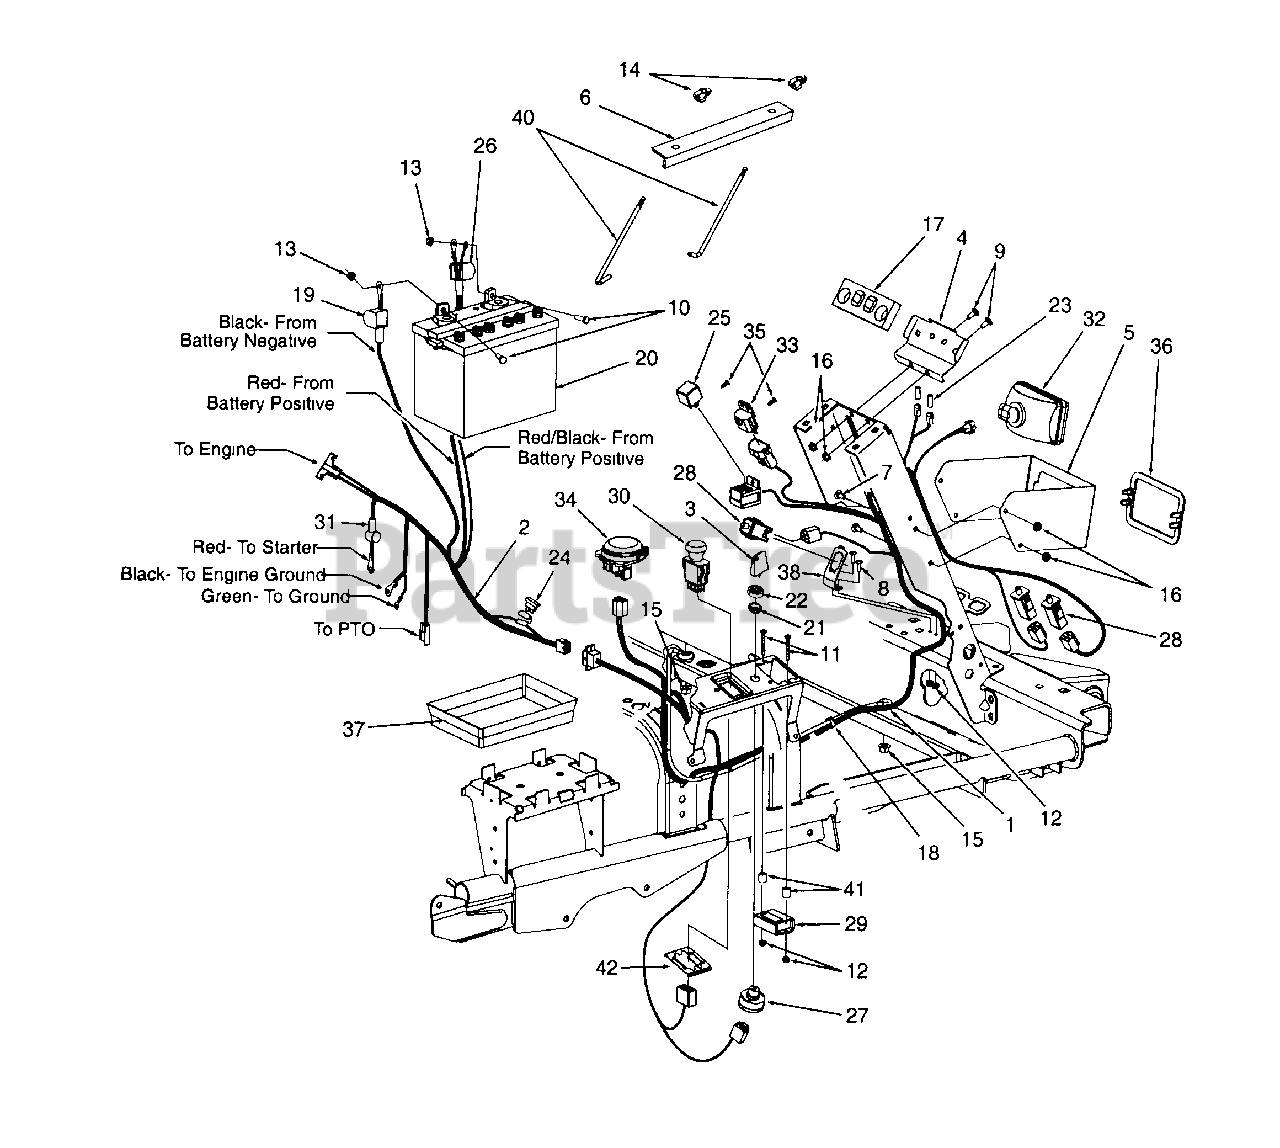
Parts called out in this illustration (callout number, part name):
1	Main Wire Harness
2	Engine Wire Harness
3	Ignition Key
7	Carriage Bolt 1/4-20 x .62
8	Machine Screw #10-24 x 5/8
9	Hex Cap Screw 1/4-20 x .50
10	Hex Cap Screw 1/4-20 x .75
11	Pan Head Cutting Screw #10-24
12	Hex Insert Lock Nut #10-24
13	Hex Sems Nut 1/4-20
14	Nylon Wing Nut 1/4-20
15	Hex Flange Lock Nut 3/8-16
16	Hex Flange Lock Nut 1/4-20
17	Indicator Light Foam Protector
18	Cable Tie
19	Battery Terminal Cover - Black
21	Ignition Switch Nut 5/8-32
22	Ignition Switch Cap
23	Indicator Bulb
24	Mini 20 Amp Fuse
25	Relay
26	Battery Terminal Cover - Red
27	Ignition Switch
28	Plunger Safety Switch
29	Hourmeter/Tachometer
30	PTO Switch
31	Terminal Cover - Red
32	Headlight Ass'y
33	Voltage Sensor
34	Seat Switch
35	Ratcheet Retainer
36	Headlight Bezel
37	Battery Tray
38	Switch Mounting Spring
40	Battery Retainer Rod
41	Spacer
42	PTO Switch Retainer Bracket
